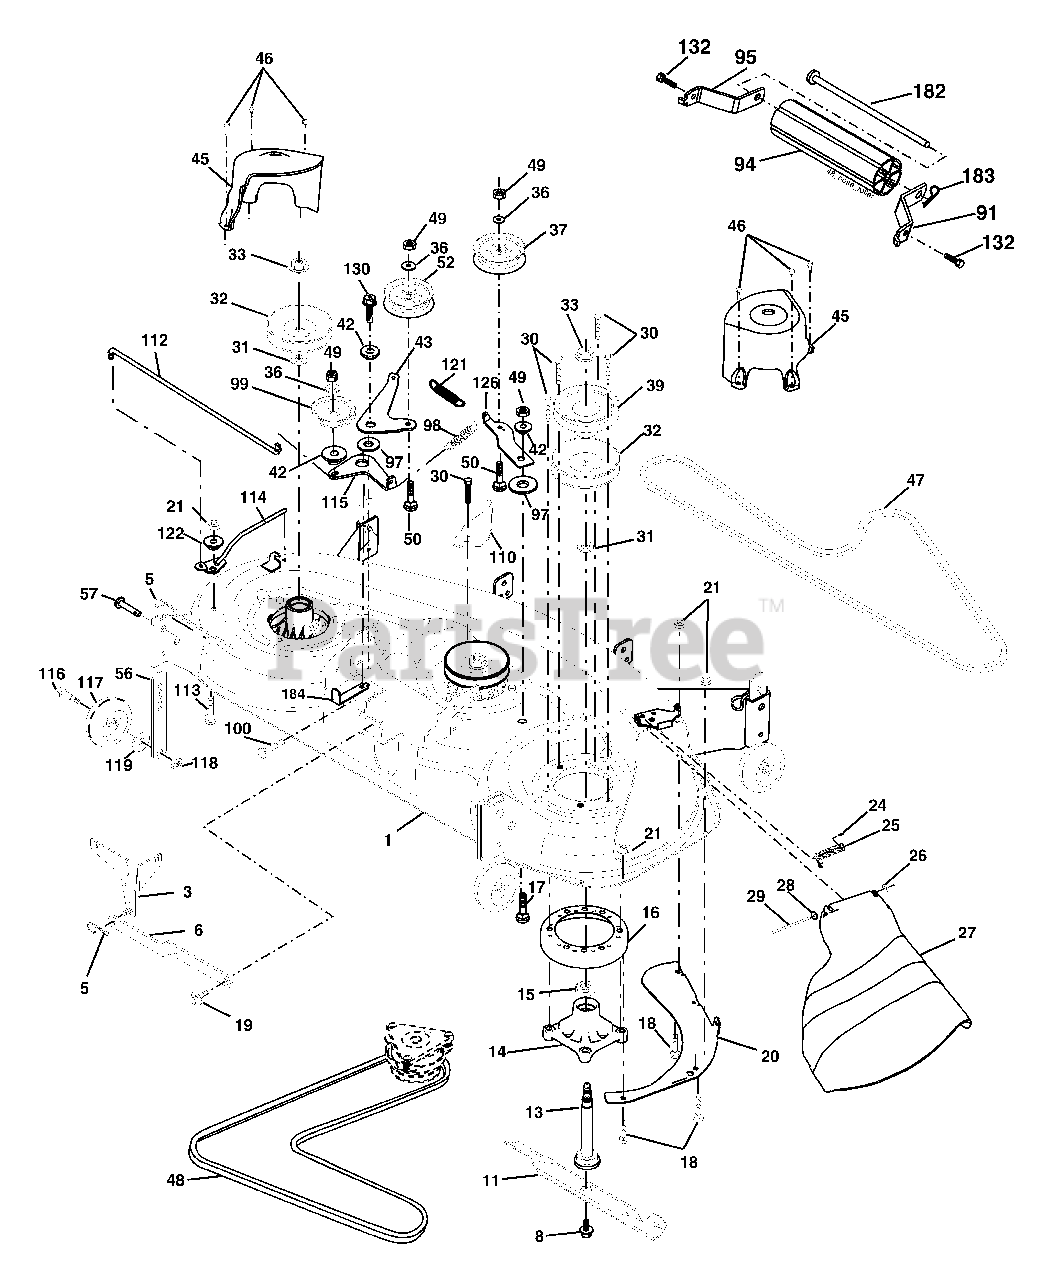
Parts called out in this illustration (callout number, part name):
1	Deck Weldment Mower 48
3	Bracket Asm., Sway Bar
5	Retainer Spring
6	Sway Bar Deck
8	Bolt 7/16 Asm. Blade
11	Blade, 48" Mulching
11	Blade, 48" Hi-Lift
13	Shaft Asm. w/Lower Bearing
14	Mandrel Asm.
15	Bearing, Ball, Mandrel
16	Stripper Mandrel Deck
17	Bolt RDHD Sq Neck 3/8-16 x 1.25
18	Bolt, Carriage 5/16-18 x 5/8
19	Bolt, Hex Hd, Shoulder 5/16-18
20	Baffle, Vortex Mower
21	Nut, Crownlock 5/16-18 Unc
24	Cap, Sleeve
25	Spring, Torsion
27	Deflector Shield
28	Washer 11/32 x 5/8 x 16 Ga.
29	Rod, Hinge
30	Screw, Thdroll Washer Head
31	Washer, Spacer Mower Vented
32	Pulley, Mandrel
33	Nut, Flg. Top Lock Cntr. 9/16
36	Washer 13/32 x 13/16 x 16 Ga.
37	Pulley, Idler, Flat
39	Pulley, Idler, Driven
42	Spacer, Retainer
43	Arm, Idler Secondary
45	Cover, Mandrel Deck
46	Screw, Thdroll. 1/4-20 x 5/8
47	V-Belt, Mower, Secondary
48	V-Belt, Mower, Primary
49	Nut, Crownlock 3/8-16 Unc
50	Bolt, Carr. 3/8-16 x 1-1/2 Gr. 5
52	Pulley Idler Flat
56	Bar Pnt Adj.
57	Pin Head Rivet
91	Bracket Asm N Roller RH
94	Roller Nose 48"
95	Bracket Asm N Roller LH
97	Washer Hardened
98	Spring Primary Drive
99	Pulley Idler "V"
100	Bolt RDHD Sqnk 3/8-16 Unc x 2
110	Arm Spring Secondary
112	Link Tension Relief Lever
113	Bolt Carr. 5/16-18 x 3/4
114	Tension Asm. Relief Lever
115	Arm Spring Tension Relief
116	Bolt, Shoulder
117	Gauge Wheel
118	Nut, Centerlock 3/8-16 Unc
119	Washer 3/8 x 7/8 x 14 Ga.
121	Spring Secondary Drive
122	Bushing Pivot Tension Relief
126	Arm, Idler, Primary Deck
130	Screw 3/8-16 x 1.0
132	Screw 3/8-16 x .75
182	Rod Roller Nose
183	Retainer Spring
184	Keeper Belt Idler
